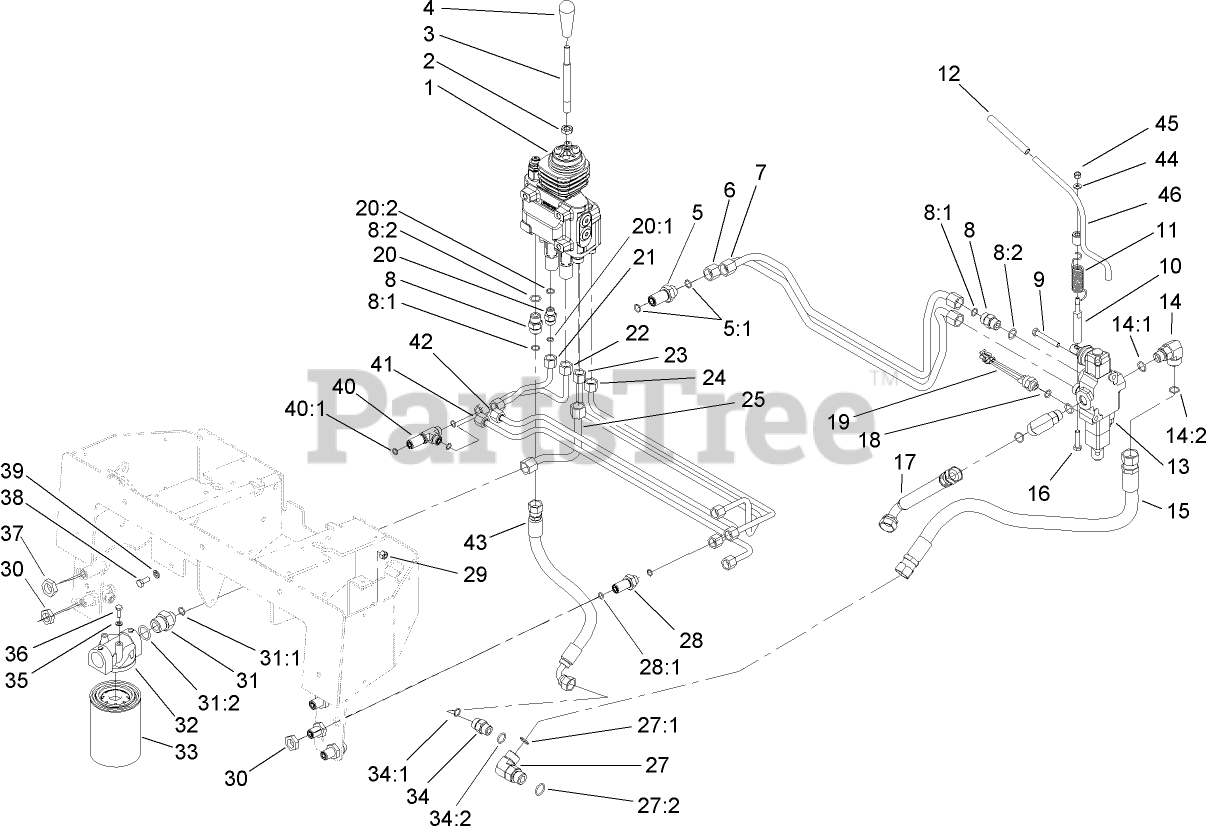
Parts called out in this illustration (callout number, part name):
1	2 SPOOL VALVE ASM
3	SHAFT-HANDLE, LOADER
5	FITTING-BULKHEAD
5:1	O-RING
6	TUBE-HYD
7	TUBE-HYD
8	FITTING-STRAIGHT
8:1	O-RING
8:2	O-RING
9	SCREW-HH
10	SPACER-HIFLO
11	SPRING-TORSION
12	CAP-ROD, TILT
13	1 SPOOL VALVE ASM
14	Fitting-Elbow, 90 DEG
14:1	O-RING
14:2	O-RING
15	HYD HOSE ASM
16	SCREW
17	HYD HOSE ASM
18	O-RING
19	SWITCH-BALL
20	FITTING-STRAIGHT
20:1	O-RING
20:2	O-RING
21	TUBE-HYD
22	TUBE-HYD
23	TUBE-HYD
24	TUBE-HYD
25	TUBE-HYD
27	FITTING-ELBOW-90
27:1	O-RING
27:2	O-RING
28	FITTING-STRAIGHT, BULKHEAD
28:1	O-RING
29	NUT-LOCK, NI
30	NUT-LOCK
31	FITTING-STR
31:1	O-RING
31:2	O-RING
32	HEAD-FILTER
33	FILTER-OIL
34	FITTING-STRAIGHT
34:1	O-RING
34:2	O-RING
35	WASHER-LOCK
36	SCREW-HH
37	NUT-BULKHEAD
38	SCREW-HH
39	WASHER-LOCK
40	FITTING-TEE, BULKHEAD
40:1	O-RING
41	TUBE-HYD
42	TUBE-HYD
43	HYD HOSE ASM
44	WASHER-FLAT
45	NUT-LOCK, NI
46	AUXILIARY LEVER ASM
